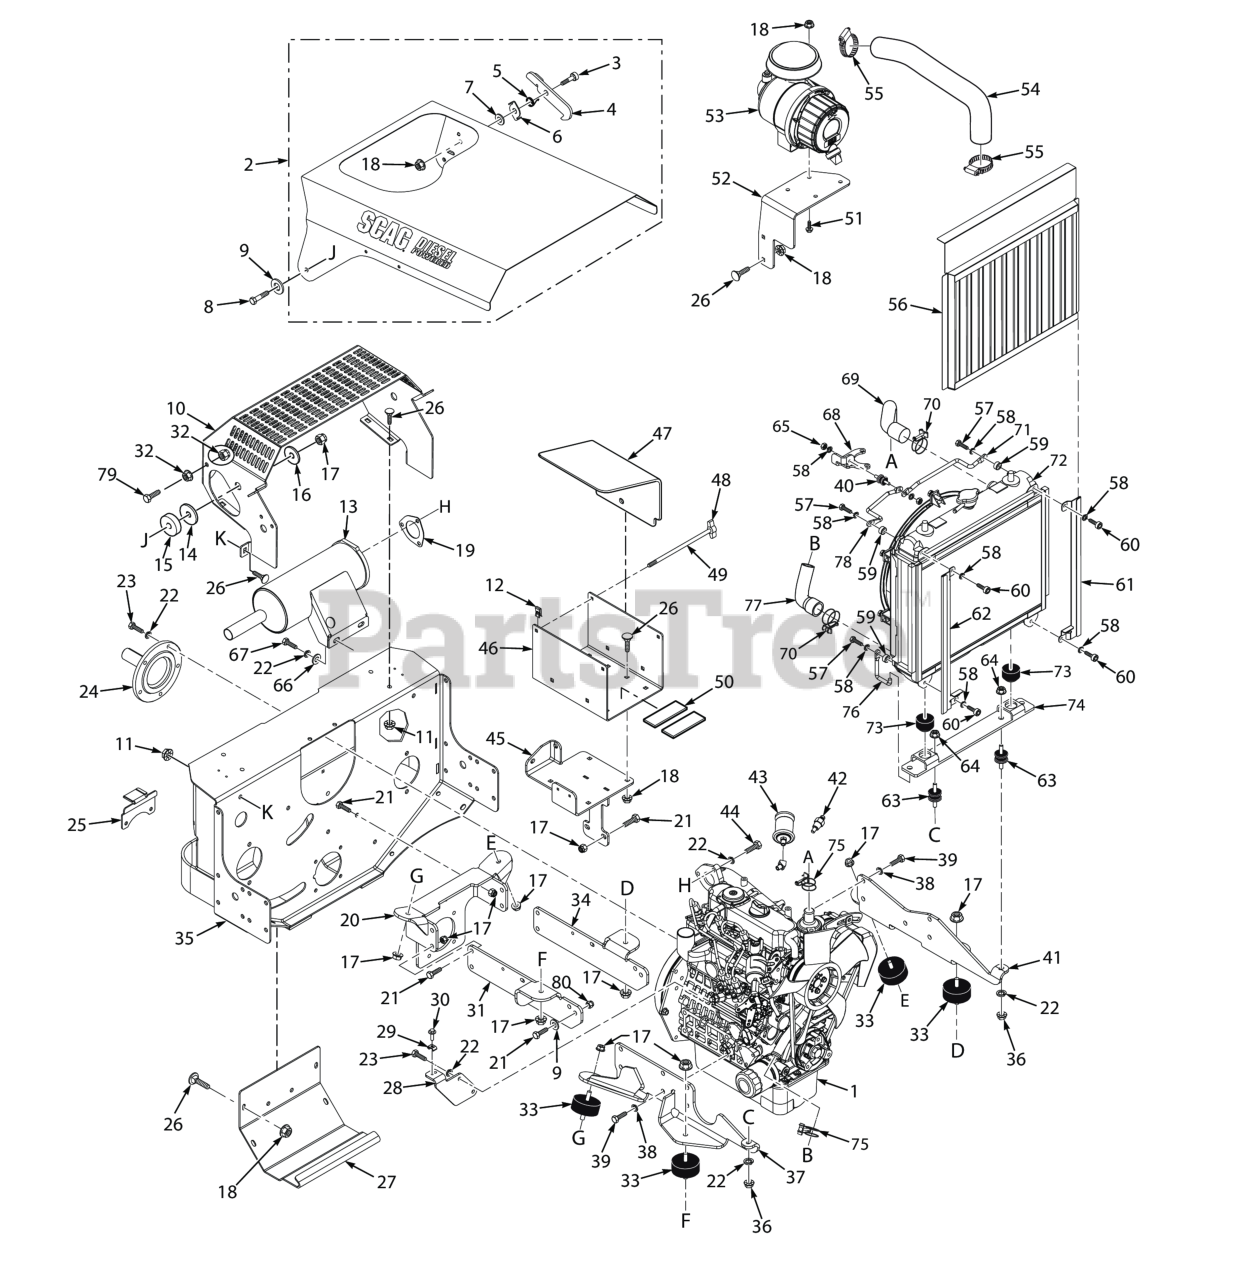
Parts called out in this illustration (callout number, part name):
1	Engine, D902 - Kubota
2	Hood Assy., STTII (Kubota Diesel)
3	Bolt, Shoulder 5/16-18 x 1/2"
4	Latch, Hood
5	Spring, Hood Latch
6	Lock, Hood Latch
7	Flatwasher, 3/8 (.406 x .812 x .065)
8	Bolt, Hex Head 3/8-16 x 1-3/4" (Kohler EFI)
9	Flatwasher, 3/8" Special (.391 x .938 x .105)
10	Guard, Muffler
11	Nut, Flange Head Elastic Stop 5/16-18
12	Bolt, Hex Head 3/8-16 x 1"
13	Muffler, Kubota
14	Disc, Anti-Friction
15	Spacer, Hood
16	Flatwasher, 3/8-.406 x 1-1-1/2 x 7 Gauge
17	HEX NUT, ELASTIC STOP LOCK, 3/8-16
18	Nut, Serrated Flange 5/16-18 (Right Front Engine Mounting, Briggs and Kohler Only)
19	Gasket, Muffler
20	Plate, Rear Engine Mount
21	Bolt, Hex Head, 3/8-16 x 1 Gr. 5
22	Lockwasher, 5/16 (.317 x .586 x .078) Helical Spring
23	Bolt, Metric Hex Head M8-1.25 x 20LG
24	Stub Shaft, (Kubota)
25	Bracket, Belt Guide
26	Bolt, 5/16-18 x .75 RHSN Carriage
27	Cover, Rear
28	Bracket, Control Mount
29	Clamp
30	SCREW, 10-32 X 3/4" SELF TAP
31	Plate, Engine Mount RH
32	NUT, 3/8-16 SERRATED FLANGE HEX HEAD
33	Mount, Engine Isolation
34	Plate, Engine Mount LH
35	Pump Mounting Plate Weldment (Diesel)
36	Nut, Metric Hex M8-1.25mm
37	Mounting Bracket Weldment RH
38	Lockwasher, 7/16� Spring
39	Bolt, Metric Hex Head M10-1.25 x 25LG
40	ISO Mount, Upper Radiator
41	Mounting Bracket Weldment LH
42	Temperature Sensor, Engine Coolant
43	Sender Unit, Oil Pressure
44	Bolt, Metric Hex Head M8-1.25 x 30LG
45	Battery Bracket Weldment (Diesel Only)
46	Battery Box w/Decal (Diesel Only)
47	Cover, Battery (Diesel Only)
48	Knob, 1/4" Wing
49	Bolt, Hex Head 1/4-20 x 8"
50	PAD, BATTERY SUPPORT
51	Cpscrw, 5/16-18 x 1"Serrated Flange Hex Head
52	Bracket, Air Cleaner Mount
53	Air Filter Assembly (Enginaire p/n 67150)
54	Hose, Air Intake
55	Clamp, 2-3/4" Max. Dia.
56	Debris Screen Assembly (With Upper Foam)
57	Bolt, Metric Hex Hd. M6-1.0 x 30mm
58	Lockwasher, 1/4� Spring
59	Spacer, Radiator
60	Capscrew, Metric M6-1.0 x 16mm
61	Debris Screen Track RH
62	Debris Screen Track LH
63	ISO Mount, Lower Radiator
64	Nut, Metric Serr. Flng. M8 x 1.25
65	Nut, Metric Hex M6 x 1
66	Flatwasher, 5/16-.344 x .688 x .065 (48V / 52V)
67	Bolt, Metric Hex Head M8-1.25 x 25LG
79	Bolt, Hex Head 3/8-16 x 1-3/4" (Kohler EFI)
80	Nut, Flange Elastic Stop Nut, 3/8-16
